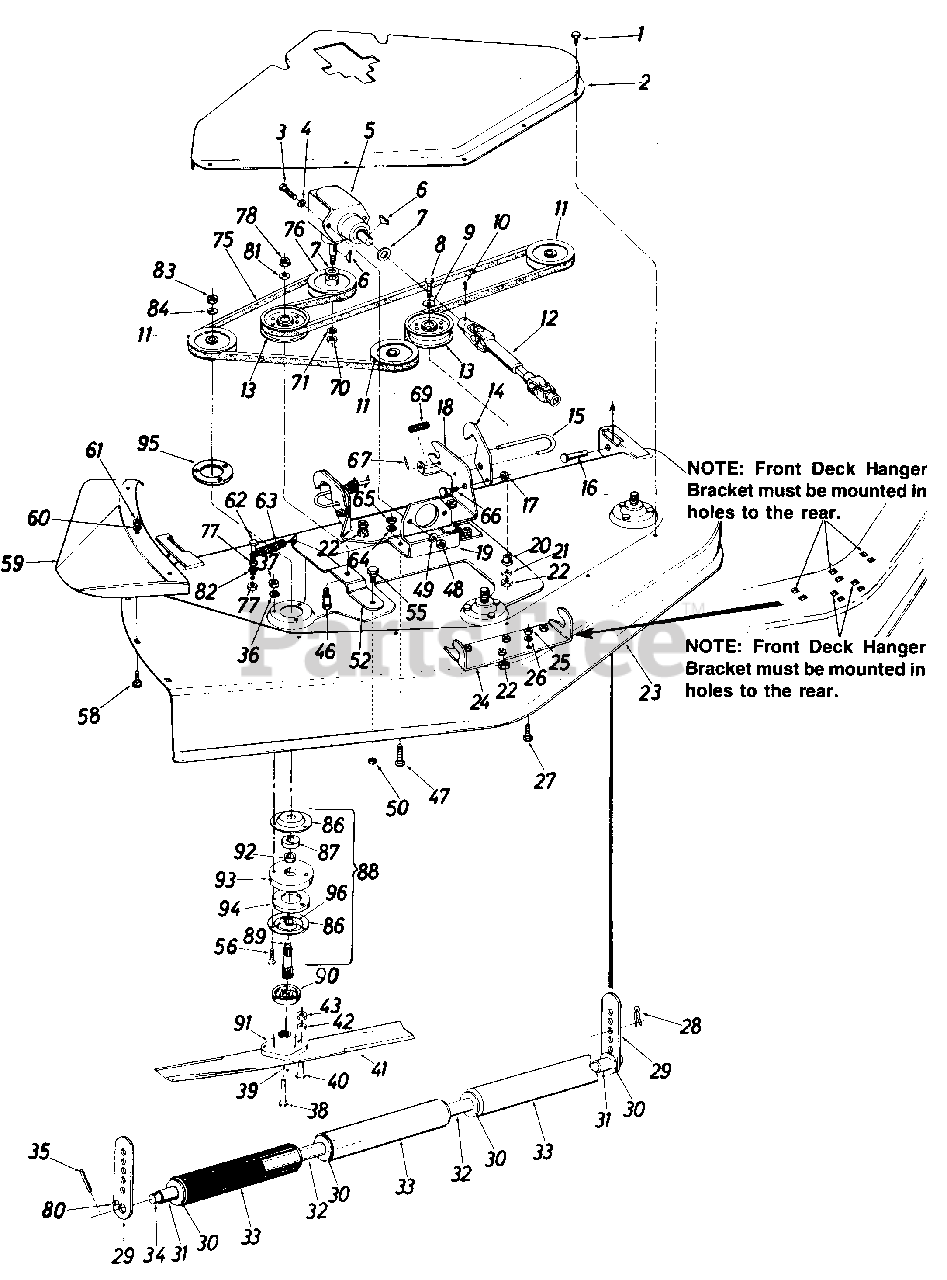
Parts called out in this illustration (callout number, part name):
1	Hex B-Tap Scr. 1/4-20 x .38" Lg.
4	Ext. L-Wash. 3/8" I.D.
5	Right Angle Drive
6	#9 Hi-Pro Key 3/16 x 3/4" Dia.
7	Fl-Wash. 29/32" I.D.
8	Hex Bolt 3/8-16 x 2.25" Lg.
9	Fl-Wash. 3/8" I.D.
10	Sq. Hd. Set Scr. 3/8-16 x .50"
11	Deck Pulley
12	Universal Drive Shaft Ass'y.
13	Deck Idler Pulley
14	Hanger Lock
15	Release Pin
16	Clevis Pin .50" Dia.
17	Hex L-Nut 5/16-18 Thd.
21	L-Wash. 3/8" I.D.
22	Hex Nut 3/8-16 Thd.
26	L-Wash. 5/16" I.D.
27	Carriage Bolt 5/16-18 x 1" Lg.*
28	Internal Cotter Pin
30	Fl-Wash. .75" I.D. x 1.5" O.D.
31	Spacer .758" I.D. x 1.25" O.D. x .530
34	Roller Shaft
35	Roll Pin 3/16 x 1.25"
36	L-Wash. 5/16" I.D.
37	Hex Cent. L-Nut 5/16-24 Thd.
38	Hex Self-Tap Scr. 3/8-24 x .75" Lg.
39	L-Wash. 3/8" I.D. H.D.
40	Hex Bolt 5/16-24 x 1" Lg.
41	Blade 17"
42	L-Wash. 5/16" I.D.
43	Hex L-Nut 5/16-24 Thd.
46	Hex Bolt 5/8-18 x 1.31 " Lg.
47	Carriage Bolt 5/16-18 x .75
48	Hex Nut 3/8-16 Thd.
49	L-Wash. 3/8" I.D.
50	Hex L-Nut 7/16-14 Thd.
56	Hex Bolt 5/16-24 x 1.5 Lg. (Grade 5)
58	Carriage Bolt 5/16-18 x75n Lg.
60	L-Wash. 5/16" I.D.
61	Hex Nut 5/16-18 Thd.
62	Hex Bolt 1/4-28 x 1-3/4" Lg.
63	Extension Spring
64	L-Wash. 5/16" I.D.
65	Hex Nut 5/16-18 Thd.
66	Shld. Bolt
67	Roll Pin 1/8" Dia.
69	Compression Spring
70	Hex L-Nut 5/8-18 Thd.
71	L-Wash. 5/8" I.D.
75	I'V"-Belt
76	Drive Pulley
77	Hex L-Nut 1/4-28 Thd.
78	Hex Cent. Lam Nut 5/8-18 Thd.
80	Spring Pin Spiral 1/4" Dia.1.00" Lg.
81	Fl-Wash..62" I.D.
82	L-Wash. 1/4" I.D.
83	Hex Jam Nut 5/8-18 Thd.
84	L-Wash. 5/8" I.D.
86	Bearing Housing
87	Ball Bearing
88	Deck Spindle Ass'y.
89	Spindle
90	Bearing Shield
91	Blade Adapter
92	Spacer
93	Spindle Spacer Plate
94	Reinforcement Plate
95	Spindle Reinforcement Plate
96	Open Bearing Housing
